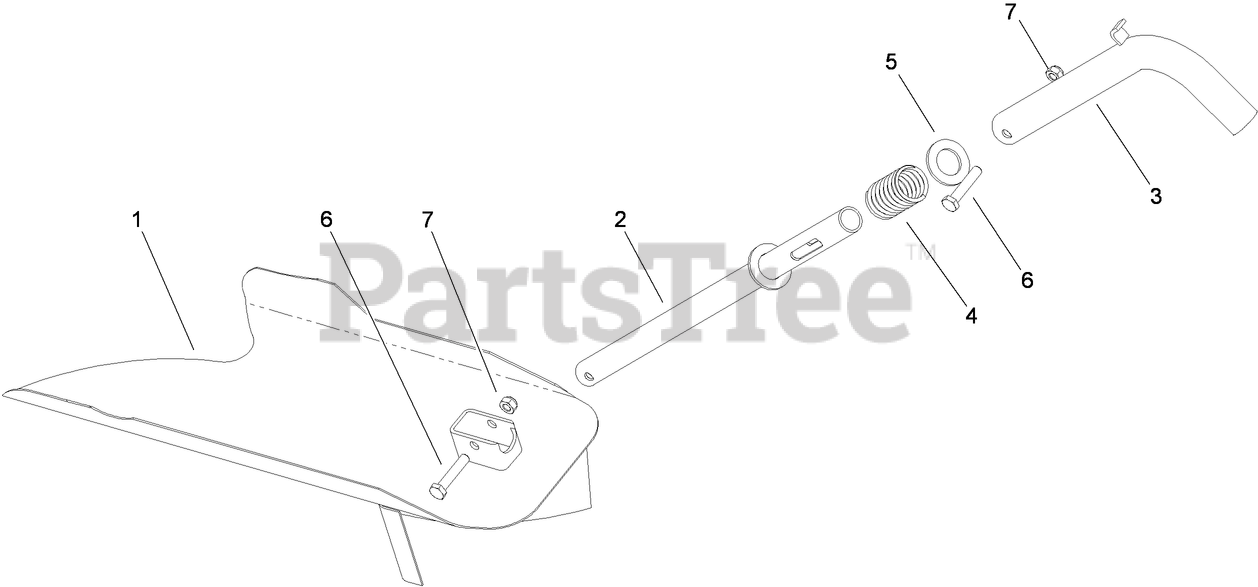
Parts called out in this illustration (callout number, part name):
1	SHIELD-MULCHING
2	TUBE-BOTTOM
3	TUBE-TOP
4	SPRING
5	WASHER
6	SCREW-HH
7	NUT-LOCK, NI
